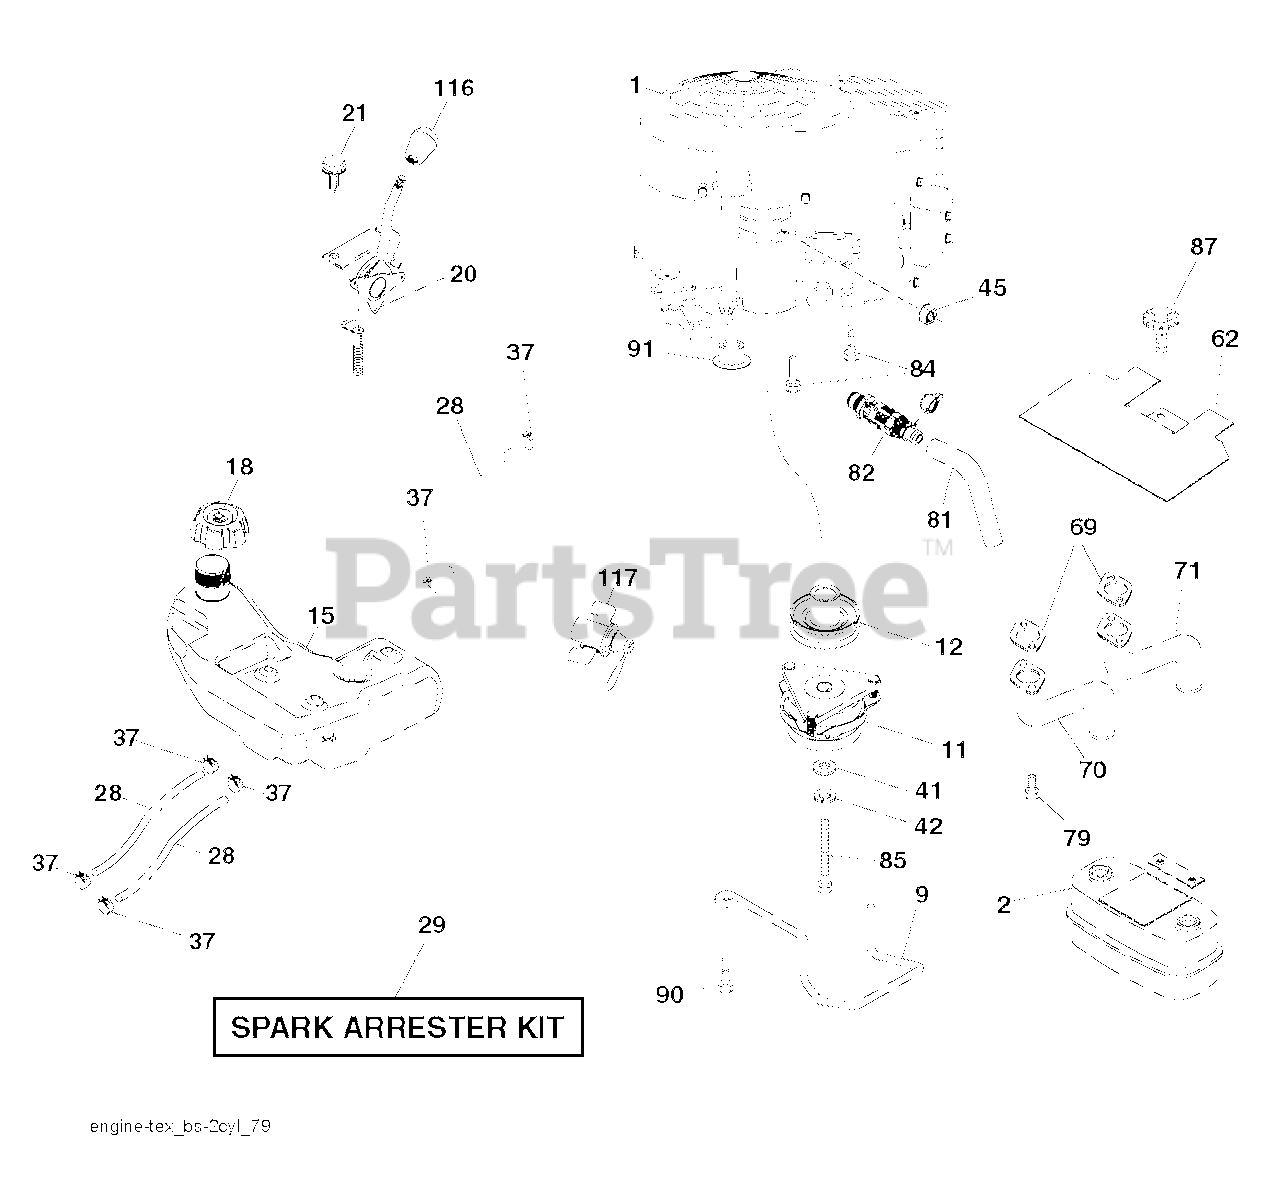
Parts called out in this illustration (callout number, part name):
2	MUFFLER.ASM.TWN.EXTNDED.DFLCTR
9	KEEPER BELT ENGINE
11	CLUTCH MZ ZTR GT.48/54"1.125"
12	PULLEY ENGINE
15	TANK.ASSY.4.GAL.2.PORT.EPA
18	CAP.ASM.FL.RITCH.3"E10.SYM.498
20	CONTROL.THROTTLE/CHOKE.PRO.45
21	SCREW.#10 X 0.750.BOS
28	LINE.FUEL.64"REAR.EMIS
29	KIT.SPARK ARRESTOR 794945 B&S
37	HOSE CLAMP
42	LOCKWASHER
45	NUT
62	SHIELD.HEAT.MUFFLER
69	GASKET.MUFFLER
70	EXHAUST.TUBE.LH.BS/TWIN
71	EXHAUST.TUBE.RH.B&S.TWIN.INTEK
79	SCREW.SOCKET.HEAD.5/16-18
81	TUBE, DRAIN OIL ASM.
82	VALUE.OIL.DRAIN
84	SCREW.3/8-16
85	BOLT HEX 7/16-20 X 3.75 GR. 5
87	BOLT, 5/16-18 X 1 3/4
90	SCREW 3/8-16X1
91	BUSHING.1.375OD
116	KNOB - SHIFT
117	VALVE FUEL RESERVE
